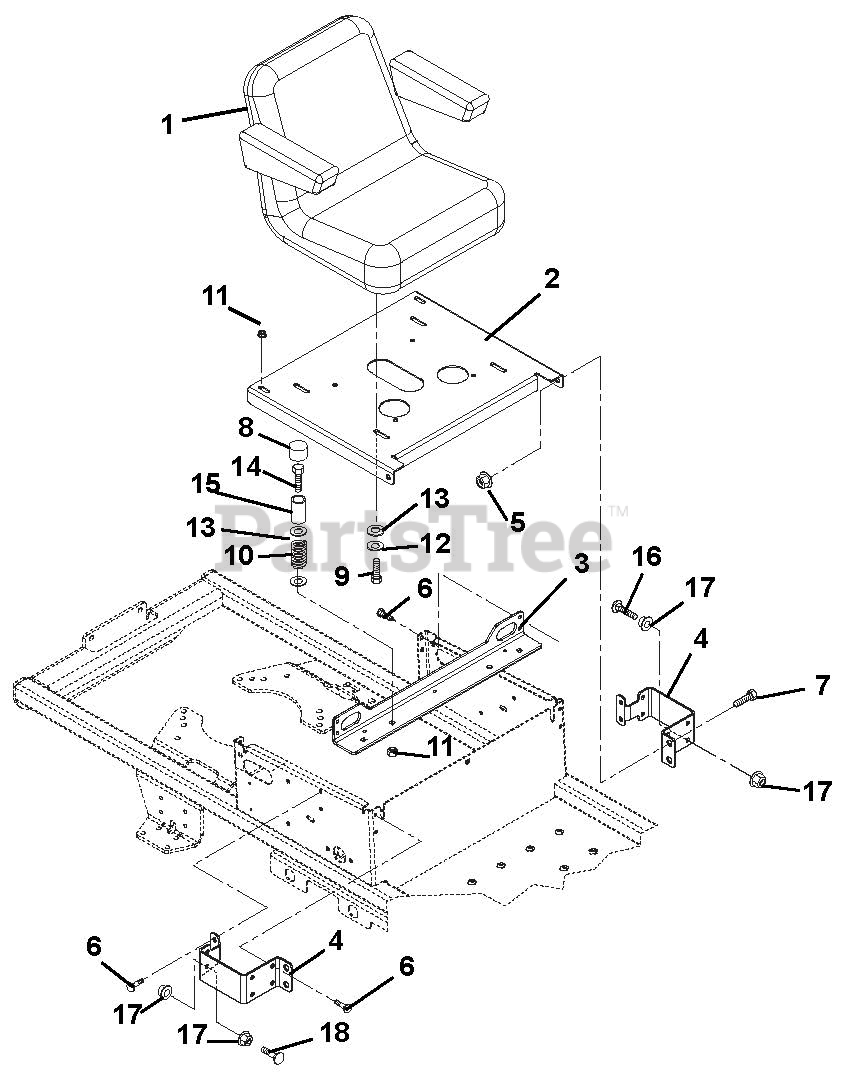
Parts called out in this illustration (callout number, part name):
1	Seat with Arm
2	Seat Plate
3	Bracket, Seat Spring
4	Bracket, Seat Pivot
5	Nut, Locking Flange Nyloc .38-16
6	Screw, Tapping .31-18 x .50
7	Bolt, Shoulder .375-16 x 1.50
9	Bolt-Hex .31-18 x 1.00 Grade 5
10	Spring, Compression 2.9 x 2.02 O.D.
11	Nut 5/16-18 Flange Nyloc
12	Washer, Locking .31 x .078
13	Washer-Flat-Steel .328 x .87 x .179
14	Bolt, Hex .31-18 x 2.75 Grade 5
15	Bushing, Sheave .344 x .502 x 1.437
16	Bolt, Round Head Square Neck .31-18 x 2.50
17	Nut, Spin Lock Flange .312-18
18	Bolt, Round Head Square Neck .31-18 x 1.75
